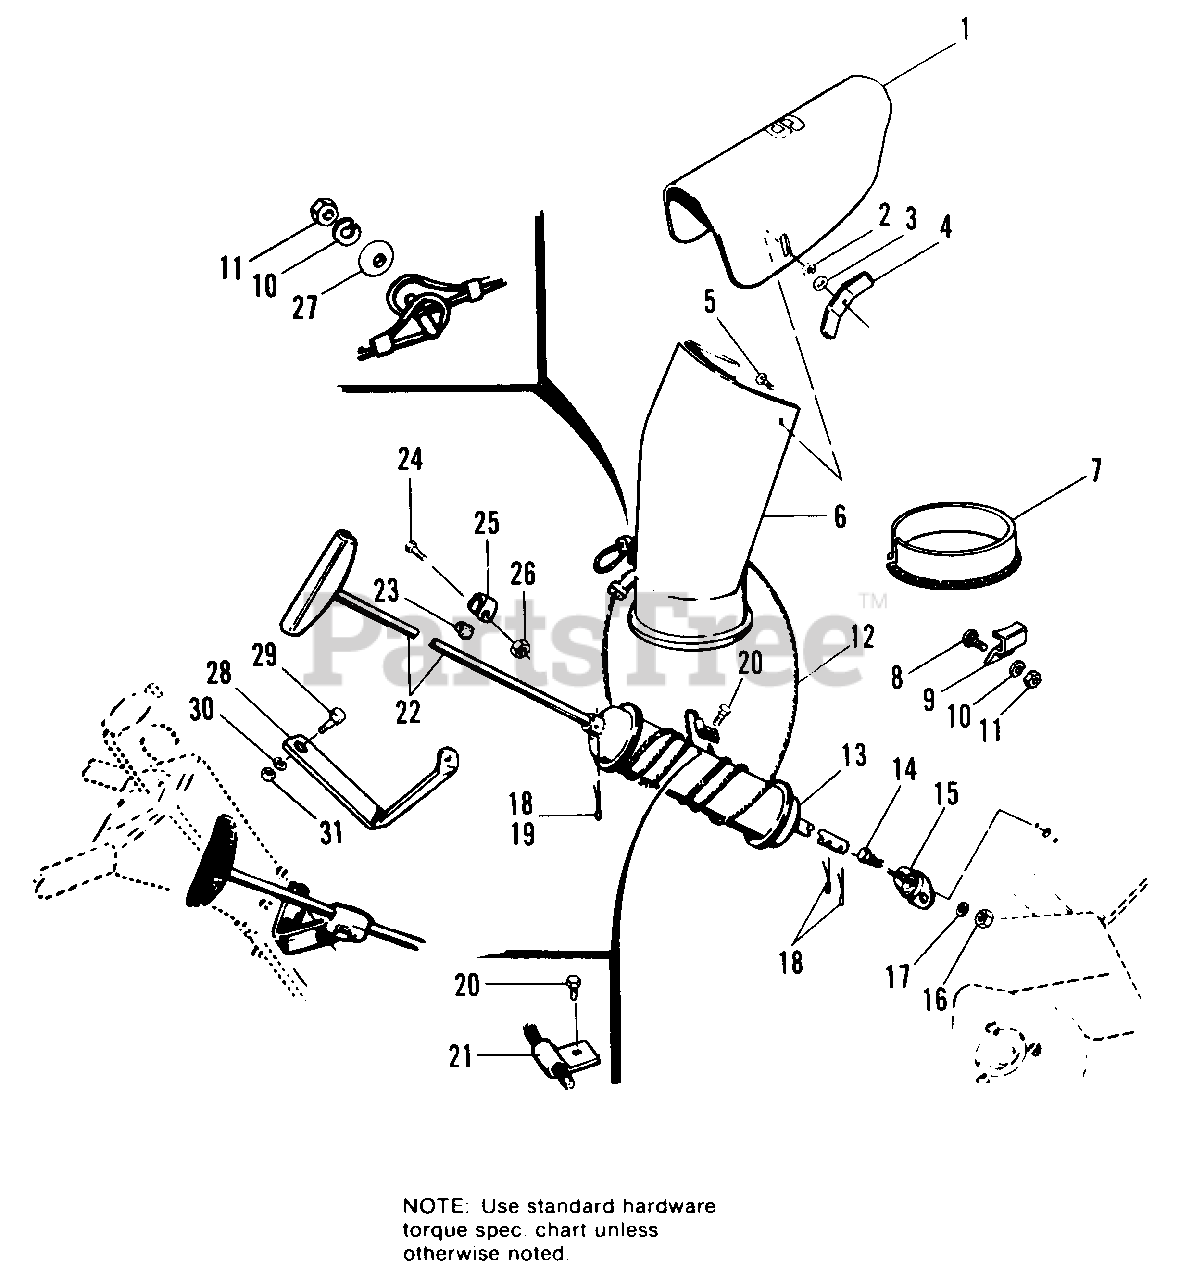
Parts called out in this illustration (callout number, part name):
1	EXTENSION, Spout
2	LOCKWASHER, Pyramdial Type, 3/8
3	WASHER, Plain, 3/8
4	NUT, Wing, 5/16-18
5	BOLT, Carriage, 5/16-18 x 3/4
6	SPOUT ASSY.
8	BOLT, Carriage, 5/16-18 x 3/4
9	PLATE, Hold Down
10	LOCKWASHER, 5/16
11	NUT, Hex, Full, 5/16-18
12	CABLE ASSY., Kit
13	TUBE ASSY., Spout Control
14	CAPSCREW, Hex Hd., 1/4-20 x 5/8
16	NUT, Hex, Full, 1/4-20
17	LOCKWASHER, 1/4
18	PIN, Cotter, 1/8 x 3/4 (990551, 990558 & 990559 Only)
18	PIN, Cotter, 3/32 x 5/8 (990482 & 990483 Only)
19	PIN, Cotter, 5/32 x 1 (990482 & 990483 Only)
20	SCREW, Taptite, 1/4-20 x 3/8
22	HANDLE ASSY.
24	CAPSCREW, Hex Hd., 5/16-18 x 1-1/4
26	LOCKNUT, Hex, 5/16-18
27	CUP, Washer
28	SUPPORT, Spout Adjusting Rod (990482, 990483, 990558 & 990559 Only)
29	CAPSCREW, Hex Hd., 1/4-20 x 1-3/4 (990482, 990483, 990558 & 990559 Only)
30	LOCKWASHER, 1/4 (990482, 990483, 990558 & 990559 Only)
31	NUT, Hex, Full, 1/4-20 (990482, 990483, 990558 & 990559 Only)
